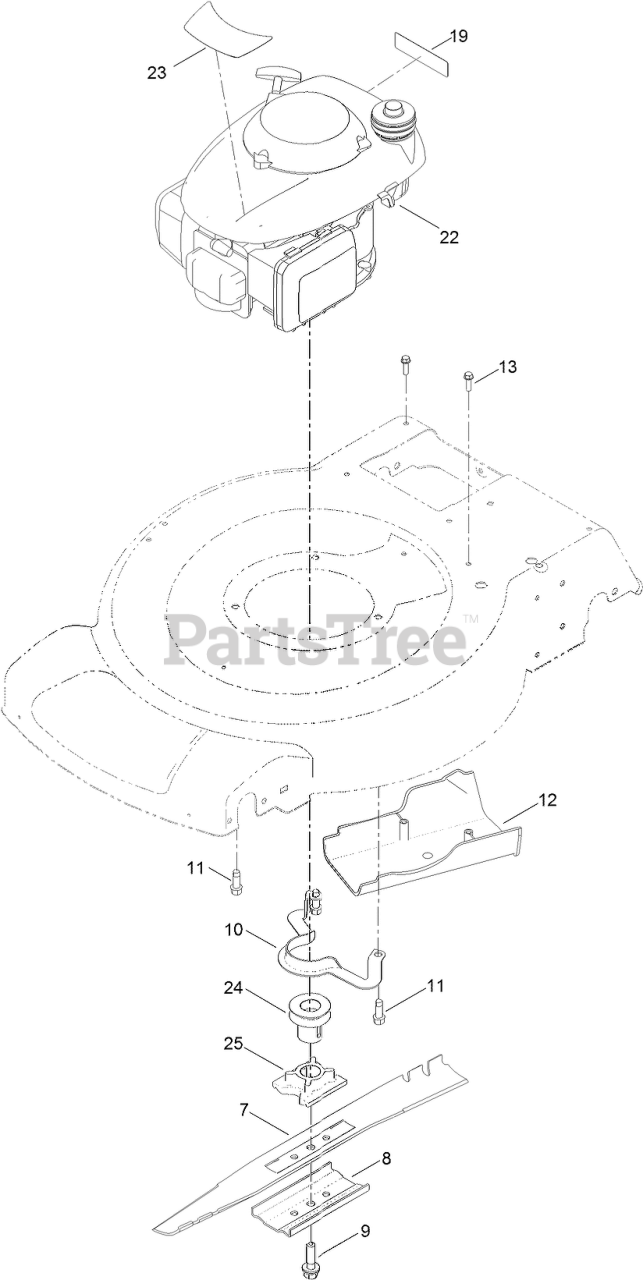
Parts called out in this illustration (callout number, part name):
7	BLADE-22 INCH
8	SUPPORT-BLADE
9	BOLT-BLADE
10	Guide-Belt
11	SCREW-TAPTITE
12	COVER-BELT
13	SCREW-HWH
19	DECAL-ARRESTER, SPARK
23	DECAL-ENGINE
24	PULLEY
25	RETAINER-BLADE
